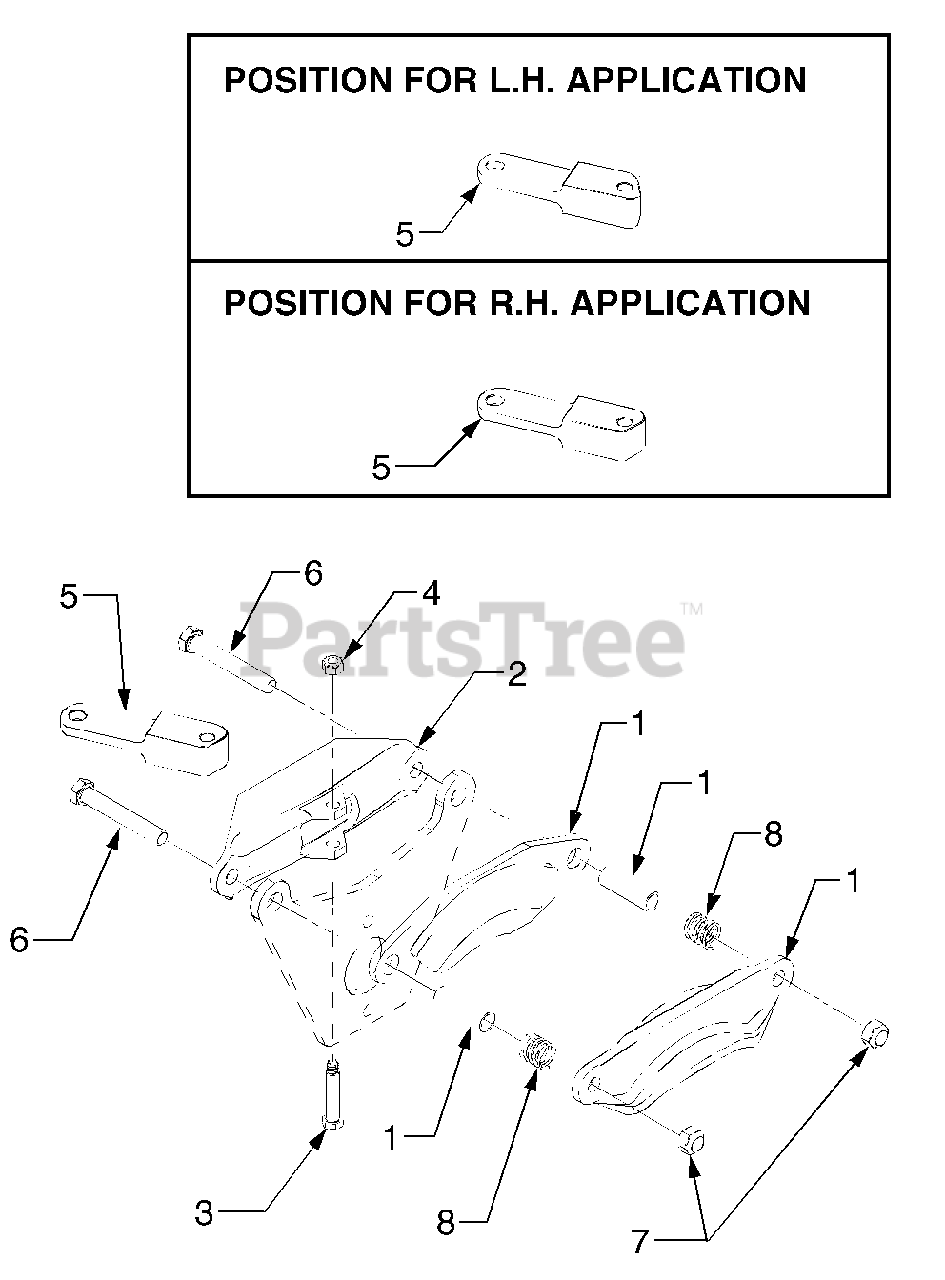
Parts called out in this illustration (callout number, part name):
1	Pad Kit, Brake
2	Bracket, Brake Actuator
3	Screw, Shoulder
4	Nut, Hex Top Lock, 1/4-20
5	Arm, Brake Actuator
6	Screw, Hex Cap, 3/8-24 x 2.5 GR5
7	Nut, Hex Lock, 3/8-24
8	Spring, Compression
